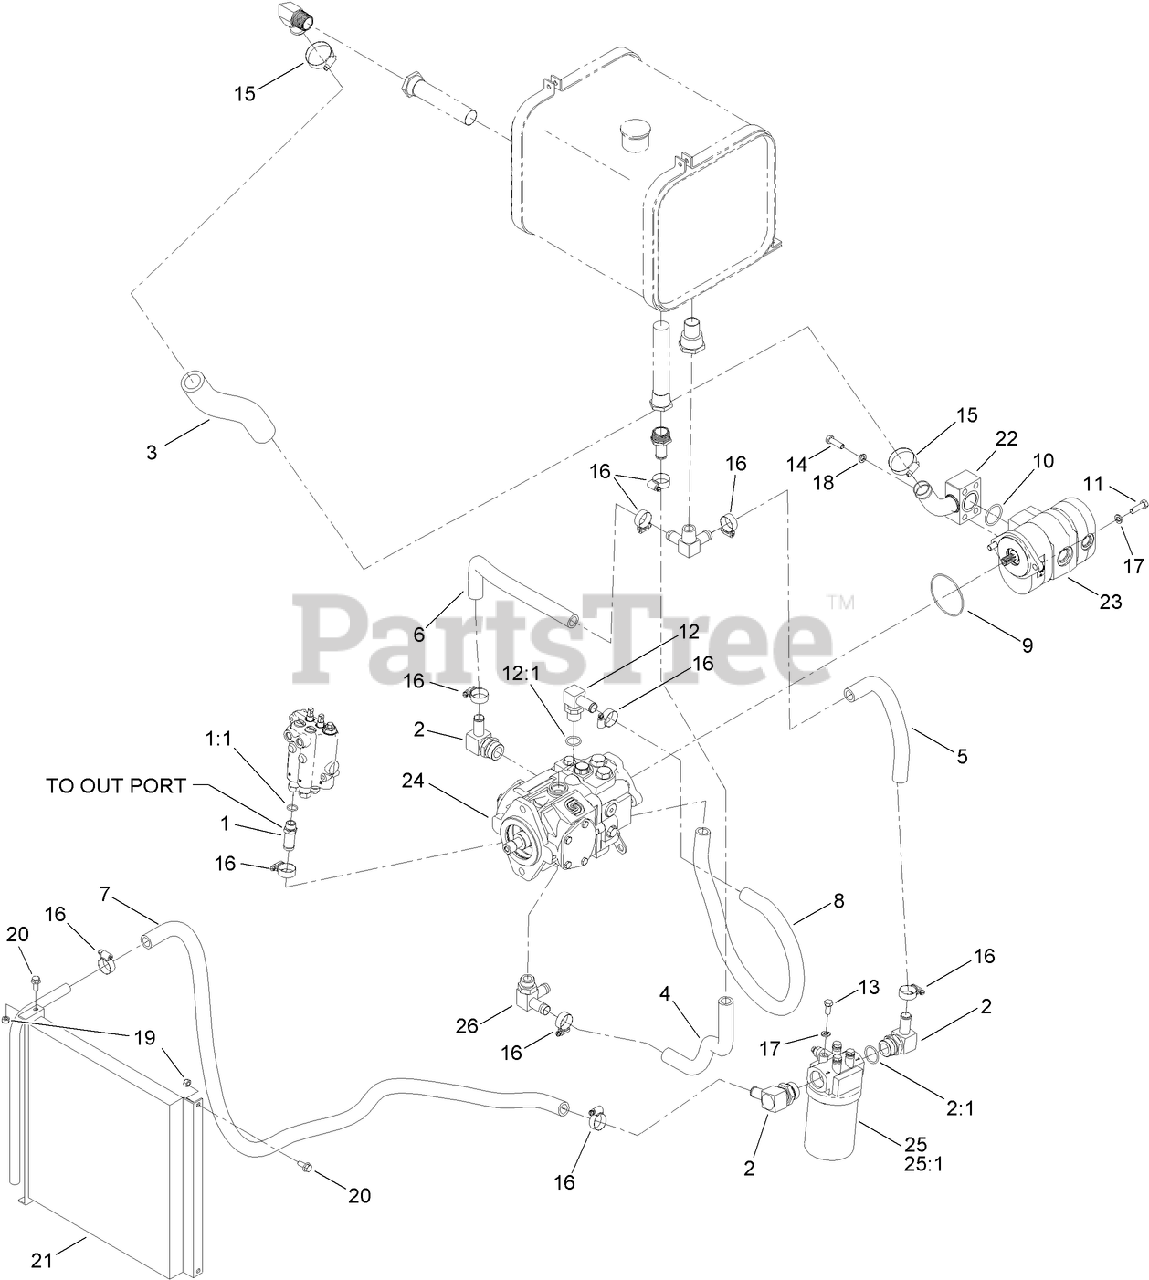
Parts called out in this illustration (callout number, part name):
1	FITTING-STRAIGHT
1:1	O-RING
2	FITTING-ELBOW, 90
2:1	O-RING
3	HOSE-SUCTION
4	HOSE-RETURN, PTO
5	HOSE-HYD
6	HOSE-HYD
7	HOSE-HYD
11	SCREW-HH
12	FITTING-ELB 90
12:1	O-RING
13	SCREW-HH
14	SCREW-HH
15	CLAMP-HOSE
16	CLAMP-HOSE
17	WASHER-LOCK
18	WASHER-LOCK
19	NUT-LOCK, NI
20	SCREW-HHF
21	COOLER-OIL
22	FLANGE-PUMP
23	HYD PUMP ASM (DOUBLE)
24	HYD VARIABLE PUMP ASM
25	OIL FILTER ASM
25:1	FILTER-HYD
